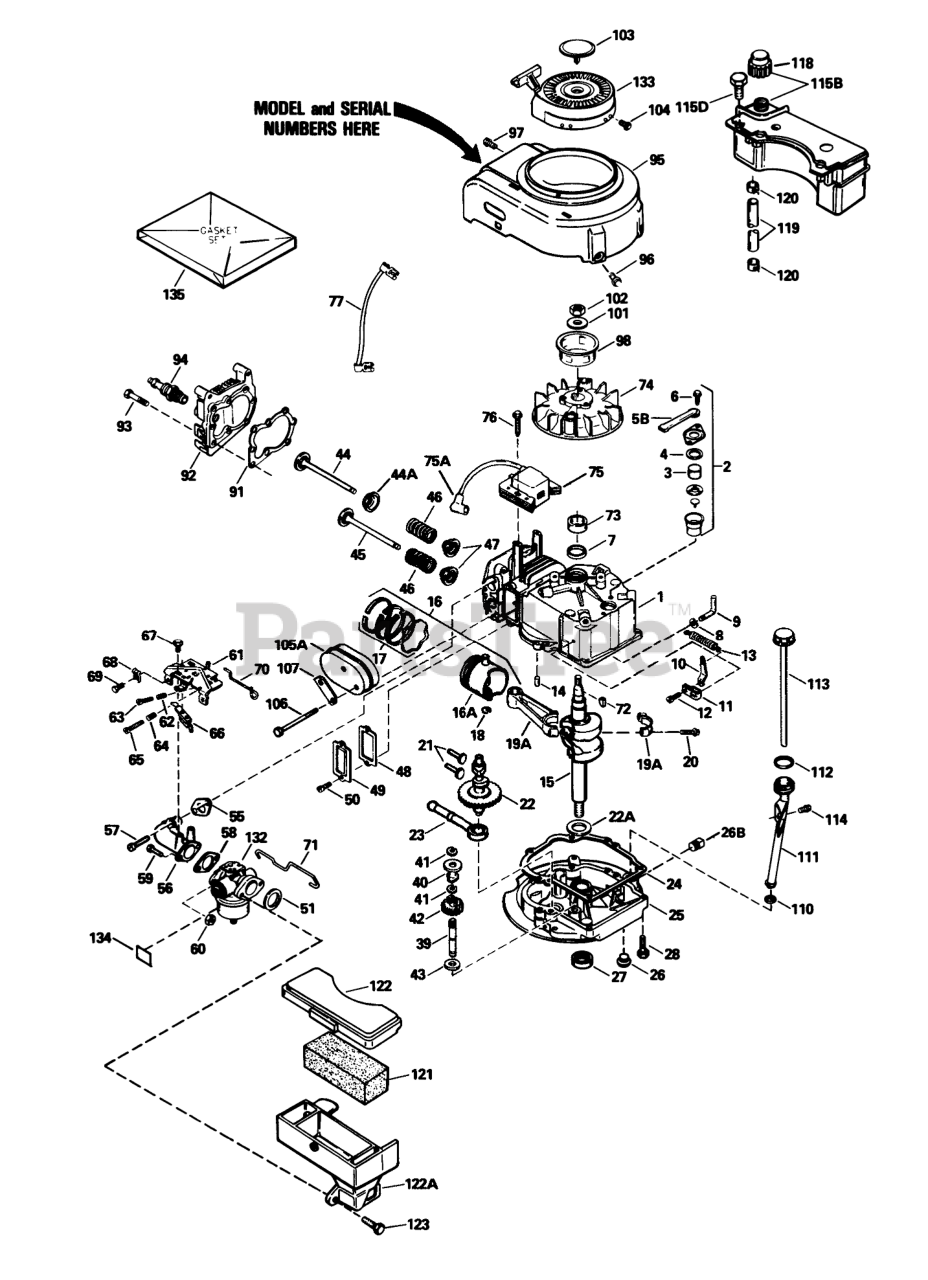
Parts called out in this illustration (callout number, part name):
1	Cylinder Assembly (Incl. Ref. #7 & 14)
2	Breather Assembly (Incl. Ref. #3-6)
3	Element-Breather
4	Gasket-Breather
5B	Tube, Breaker
6	Screw (10-24 x 9/16)
7	Seal-Oil
8	Washer-Flat
9	Rod-Governor (Incl. Ref. #8)
10	Governor Lever
11	Clamp-Lever, Governor
12	Screw
13	Spring Governor
14	Pin-Dowel
15	Crankshaft Assembly
16	Piston-Pin & Ring Assy. (Std.) (Incl. Ref. #16A, 17 & 18)
16	Piston-Pin & Ring Assembly (.010 oversize) (Incl. Ref. #16A, 17 & 18)
16	Piston-Pin & Ring Assembly (.020 oversize) (Incl. Ref. #16A, 17 & 18)
16A	Piston & Pin Assembly (Std.) (Incl. Ref. #18)
16A	Piston & Pin Assembly (.010 oversize) (Incl. Ref. #18)
16A	Piston & Pin Assembly (.020 oversize) (Incl. Ref. #18)
17	Ring Set-Piston (Std.)
17	Ring Set, Piston(.0100versize)
17	Ring Set (.020" OS)
18	Ring-Retaining, Piston Pin
19A	Rod Assembly-Connecting (Incl. Ref. #20)
20	Bolt-Rod, Connecting
21	Lifter-Valve
22	Camshaft(Mech.Comp. Release)
22A	Washer-Thrust
23	Oil Pump ASM
24	Gasket
25	B Flange-Mounting (Incl. Ref. #26, 26B, 27 & 39)
26	Plug Oil Drain
26B	Plug-Pipe
27	Seal-Oil
28	Screw (1/4-20 x 1-1/4)
39	Shaft-Governor
40	Spool-Governor
41	Ring-Retaining
42	Gear Assembly-Governor (Incl. Ref. #43)
43	Washer
44	Valve-Intake (Std.) (Incl. Ref. #47)
44	Valve-Intake (1/32" oversize) (Incl. Ref. #47)
44A	Seal Assy., Intake
45	Valve-Exhaust (Std.) (Incl. Ref. #47)
45	Valve-Exhaust (1/32" oversize) (Incl. Ref. #47)
46	Spring-Valve
47	Cap-Valve, Spring
48	Gasket-Cover, Valve
49	Cover-Valve
51	Gasket-Cleaner, Air
55	Gasket-Intake Pipe
56	Pipe-Intake (Incl. Ref. #55)
57	Screw (1/4-20 x 1)
59	Screw (1/4-28 x 7/8)
60	Nut and Lock Washer (1/4-28)
61	Bracket Assembly-Control (Incl. Ref. #62-66)
62	61709/GIL1515A/95-5
63	Screw
64	Spring-Compression
65	Screw
66	Terminal
67	Screw (10-24 x 9/16)
68	Conduit
69	Screw (10-32 x 3/8)
70	2035A67 ADD.ASSEMBL
71	Link-Throttle
72	Key-Flywheel
74	Flywheel
75	Solid State
75A	Cover-Spark Plug
76	Screw
77	Wire-Ground
91	Gasket-Cylinder Head
92	Head-Cylinder
93	Screw (5/16-18x1-1/2)
94	Spark Plug-Resistor (R J19 L M)
95	Housing-Blower
96	Screw (1/4-20 x 1/2)
97	Screw (10-24 x 9/16)
98	Hub-Starter
101	Washer-Belleville
102	Nut-Flywheel
103	Plug Starter
104	Screw, Hex Hd.
105A	Muffler
107	Plate-Lock
111	Oil Fill Tube
113	Dipstick
114	Screw (10-32 x 1/2)
115B	Tank Assembly (Incl. Ref. #118 & 120)
115D	Screw (10-32 x 35/64)
118	Cap-Fuel
119	Line-Fuel
120	Clamp-Line, Fuel
121	Filter-Air Cleaner
122	Cover Air Cleaner
122A	Body Air cleaner
132	Carburetor (Incl. Ref. #58)
133	Starter-Rewind
134	Decal-Primer
135	Gasket Set (Incl. Items Marked )
